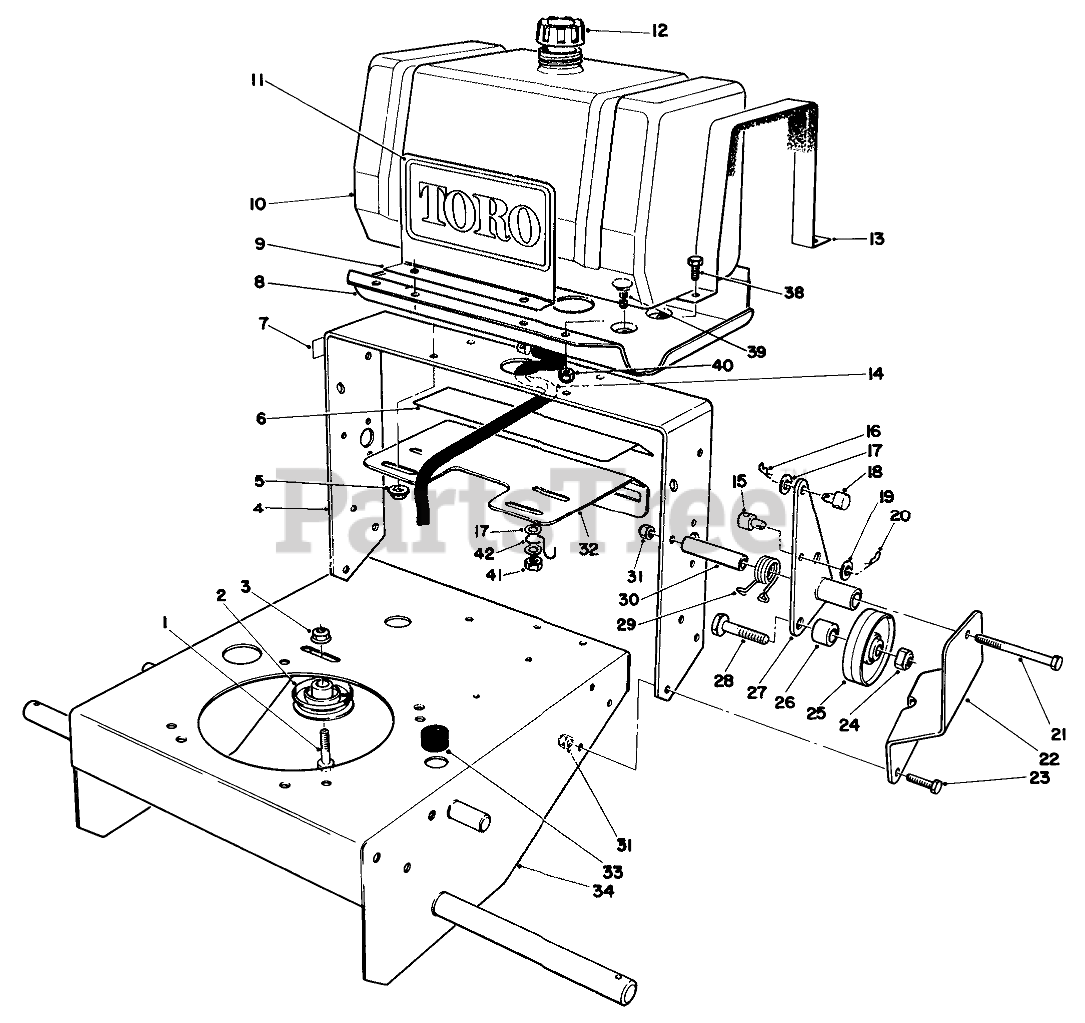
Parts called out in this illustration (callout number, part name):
1	SCREW-HH
2	PULLEY-IDLER
3	NUT-HF
4	Frame-Rear
5	NUT-HF
6	Decal-Ground Speed
7	Decal-Fuel Shut Off
8	PLATE-FUEL TANK
9	DECAL-PLATE
10	TANK-FUEL
11	DECAL
12	GAS CAP ASM
13	STRAP ASM
14	HOSE-FUEL
15	ROD FITTING
16	PIN-COTTER
17	WASHER-PLAIN
18	ROD FITTING
19	WASHER-PLAIN
20	PIN-COTTER
21	SCREW-HH
22	Support-Idler L.H.
23	SCREW-HH
24	NUT-LOCK, NI
25	IdlerWheel
26	WHEEL IDLER SPACER
27	LH IDLER BRKT WA
28	SCREW-LEVELER
29	SPRING-TORSION, LH
30	PIVOT-IDLER SPACER
31	NUT-LOCK, NI
32	CONTROL PLATE R
33	GROMMET
34	Frame
38	SCREW-HH
39	SCREW-CARR
40	NUT-LOCK, NI
41	NUT-LOCK, NI
42	GAS LINE CLIP
